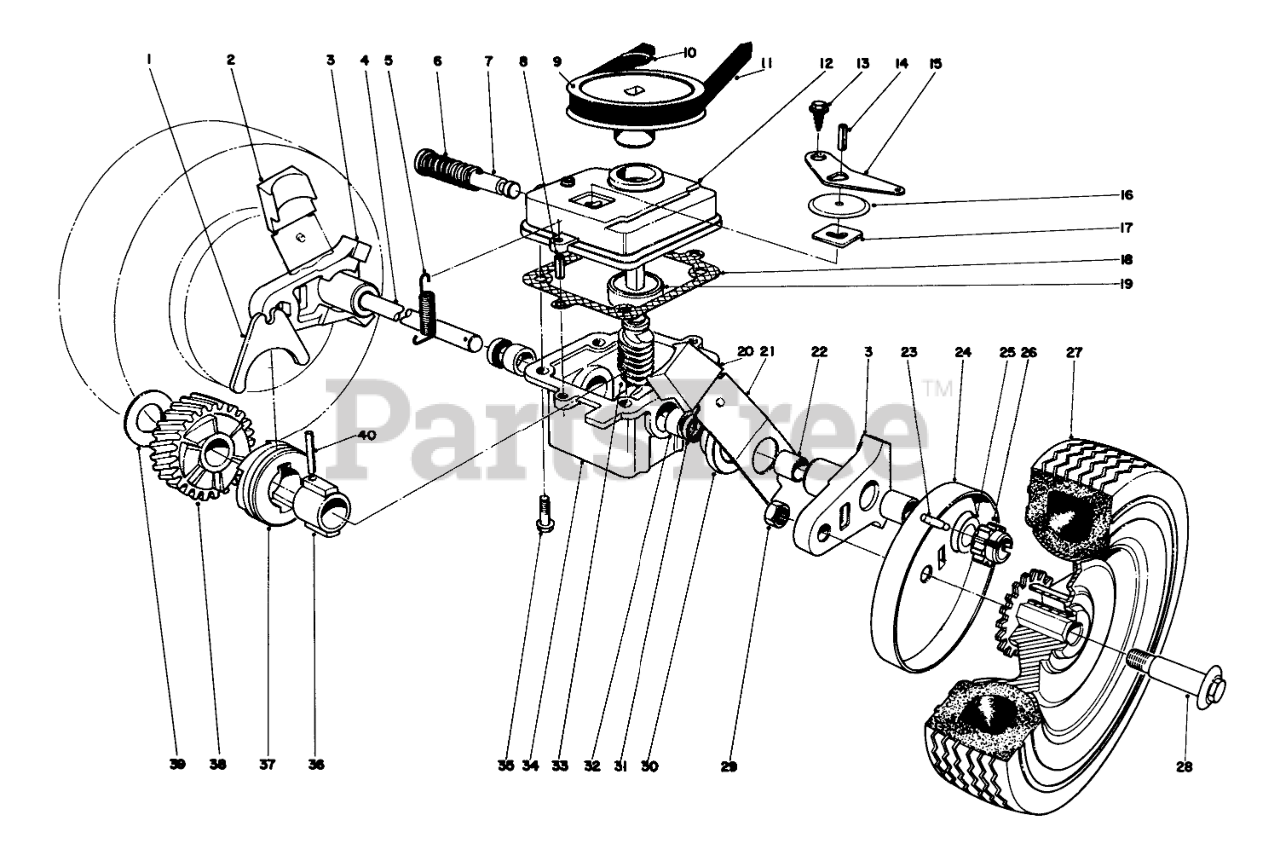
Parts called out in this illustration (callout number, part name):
1	SHIFTER FORK
2	Arm Knob
3	Pivot Arm (Incl. Ref. No. 22)
4	Drive Shaft
5	TENSION SPRING
6	SPRING
7	Shift Rod
8	3/16 X 1/2 ROLL PIN
9	PULLEY
10	PUSH-ON 93-3236
11	V BELT
12	GEAR CASE COVER
13	Screw
14	PIN-ROLL
15	SHIFTER ARM
16	TRANS DUST COVER
17	LATCH PLATE
18	GASKET
19	Bearing
20	Arm Knob
21	Spring Arm
22	BUSHING
23	PIN-GROOVED
24	WHEEL COVER
25	WASHER-THRUST
26	Pinion
27	Bushing
29	Nut
30	End Cap
31	Seal
32	Bushing
33	WORM SHAFT
34	WW GEAR CASE ASM
35	Screw
36	SLEEVE
37	CLUTCH JAW
39	THRUST WASHER
40	COIL PIN
